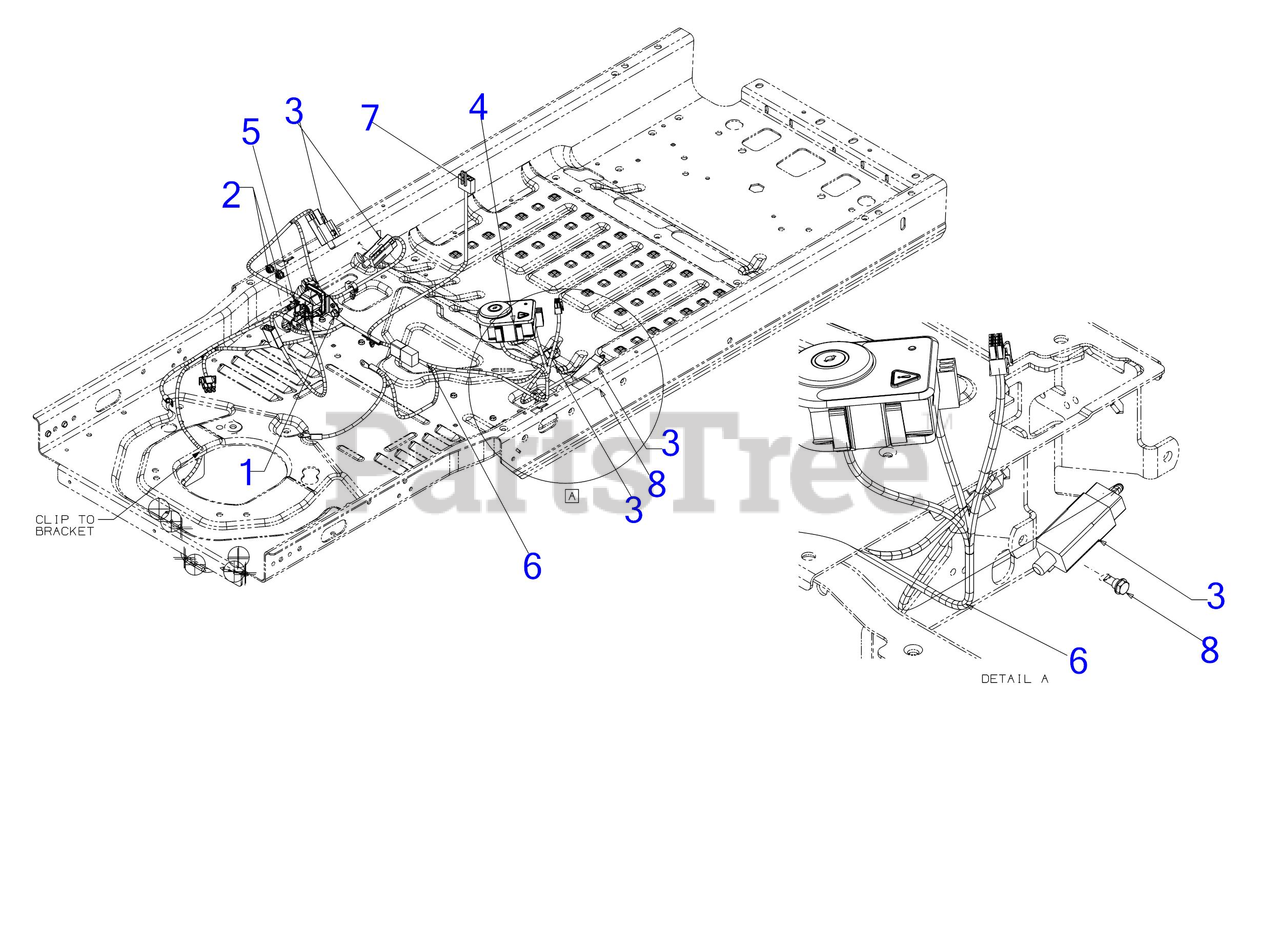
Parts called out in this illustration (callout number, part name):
1	SCREW 1/4-20X.625
2	FLANGE LOCK NUT
3	INTERLOCK SWITCH (NO/NC)
4	IGNITION SWITCH MODULE
5	SOLENOID-12V 100A
6	JUMPER HARNESS
7	MAIN HARNESS (ELECTRIC PTO)
8	SHOULDER SCREW
